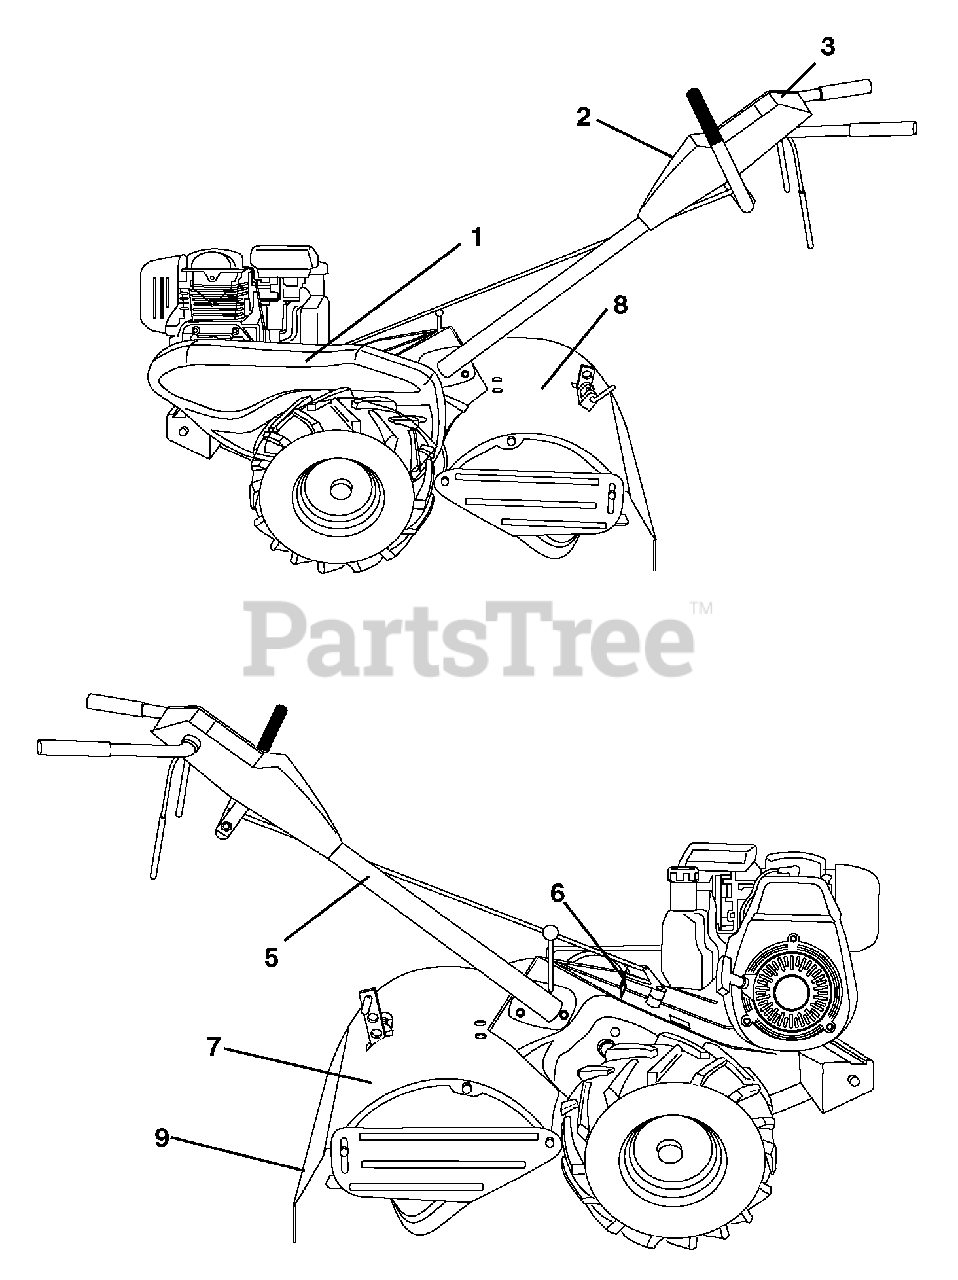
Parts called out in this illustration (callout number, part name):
1	Decal, Blt Grd
2	Decal, Logo
3	Decal, CNTRL PNL
5	Decal, Hand Placement
6	Decal, Shift Indicator
7	Decal, Warning
8	Decal, Tineshield
9	Decal, Warning, Rotating Tines
